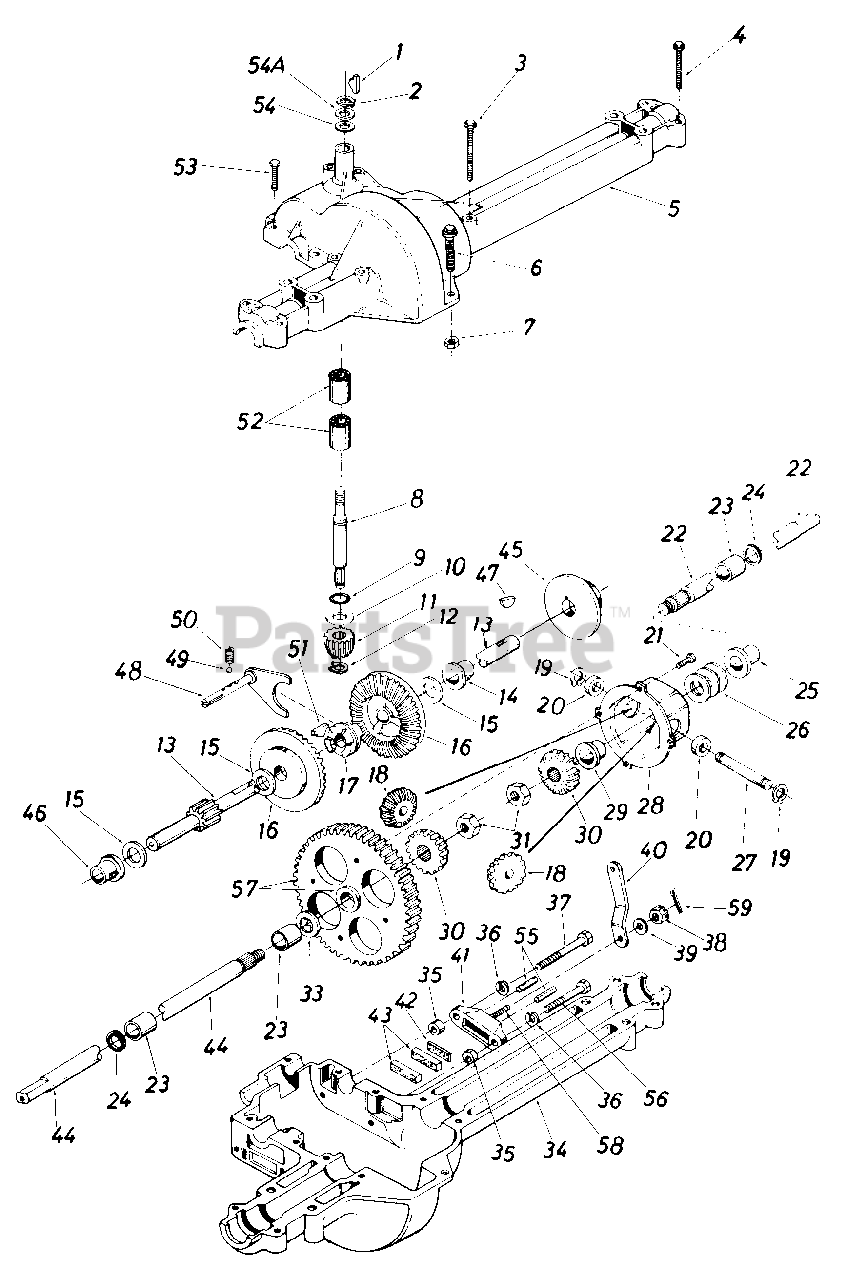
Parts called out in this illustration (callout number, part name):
1	#4 Hi-Pro Key 3/32 x 5/8" Dia.
2	Snap Ring .625" Shaft
3	Hex Bolt 1/4-20 x 1.75" Lg.
4	Hex Bolt 1/4-20 x 1.25" Lg.
5	Upper Housing
6	Hex Fl-Bolt 1/4-20 x .88" Lg.
7	Hex Nut 1/4-20 Thd.
8	Input Shaft
9	Square Seal 5/8" I.D.
10	Thrust Washer 5/8" I.D. x 1.25" O.D.
11	Pinion Input 14T
12	Retaining Ring 7/16" Ext.
13	Drive Shaft R.H.
14	Flange Brg. 5/8" I.D. x 3/4" Lg.
15	Fl-Wash. 5/8" I.D. x 1.0" O.D. x .020" Thk.
16	Bevel Gear 42T
17	Clutch Collar
18	Miter Gear 15T
19	Snap Ring
20	Thrust Bearing 1/2" I.D. x 1.0" O.D.
21	Pan Head Scr. 1/4-20 x .50" Lg. w/Patch
22	Axle R.H.
23	Sleeve Bearing 3/4" I.D. x 1.0" Lg.
24	Oil Seal 3/4" I.D.
25	Flange Bearing 3/4" I.D. x 15/16" Lg.
26	Fl-Wash. .760" I.D. x 1.49" O.D.
27	Cross Shaft
28	Differential Housing Ass'y.
30	Miter Gear
31	Hex Ins. L-Nut 1/2-20 Thd.
33	Fl-Wash. .760" I.D. x 1.49" O.D.
34	Lower Housing
35	Spacer .53" O.D. x 3/8 Lg.
36	L-Wash. 1/4" I.D.
37	Hex Bolt 1/4-20 x 1.50" Lg. Grade 5
38	Castle Nut 5/16-24 Thd
39	Fl-Wash. .344" I.D. x .875" O.D.
40	Actuating Arm R.H.
41	Brake Yoke
42	Puck Plate
43	Brake Puck
44	Axle L.H.
45	Brake Disc
46	Flange Bearing 5/8" I.D. x 15/16" Lg.
47	Woodruff Key 3/16 x 5/8 HT
48	Shift Fork Ass'y.
49	Ball Detent.250" Dia.
50	Spring Detent
51	#9 Hi-Pro Key 3116" x 3/4" Dia. HT
52	Needle Brg. 5/8" I.D. x 1/2" Lg.
53	Hex Bolt 1/4-20 x 1.00" Lg.
54	Fl-Wash. 5/8" I.D. x .030
54A	Fl-Wash. 5/8" I.D. x .040
55	Actuating Pin 5/16" Dia.
56	Hex Bolt 1/4-20 x 1.50" Lg. Grade 5
57	Differential Gear 72T Ass'y. w/Bearing
58	Sq. Hd. Bolt 5/16-24 Thd.
59	Cotter Pin 3/32" Dia. x .50" Lg.
